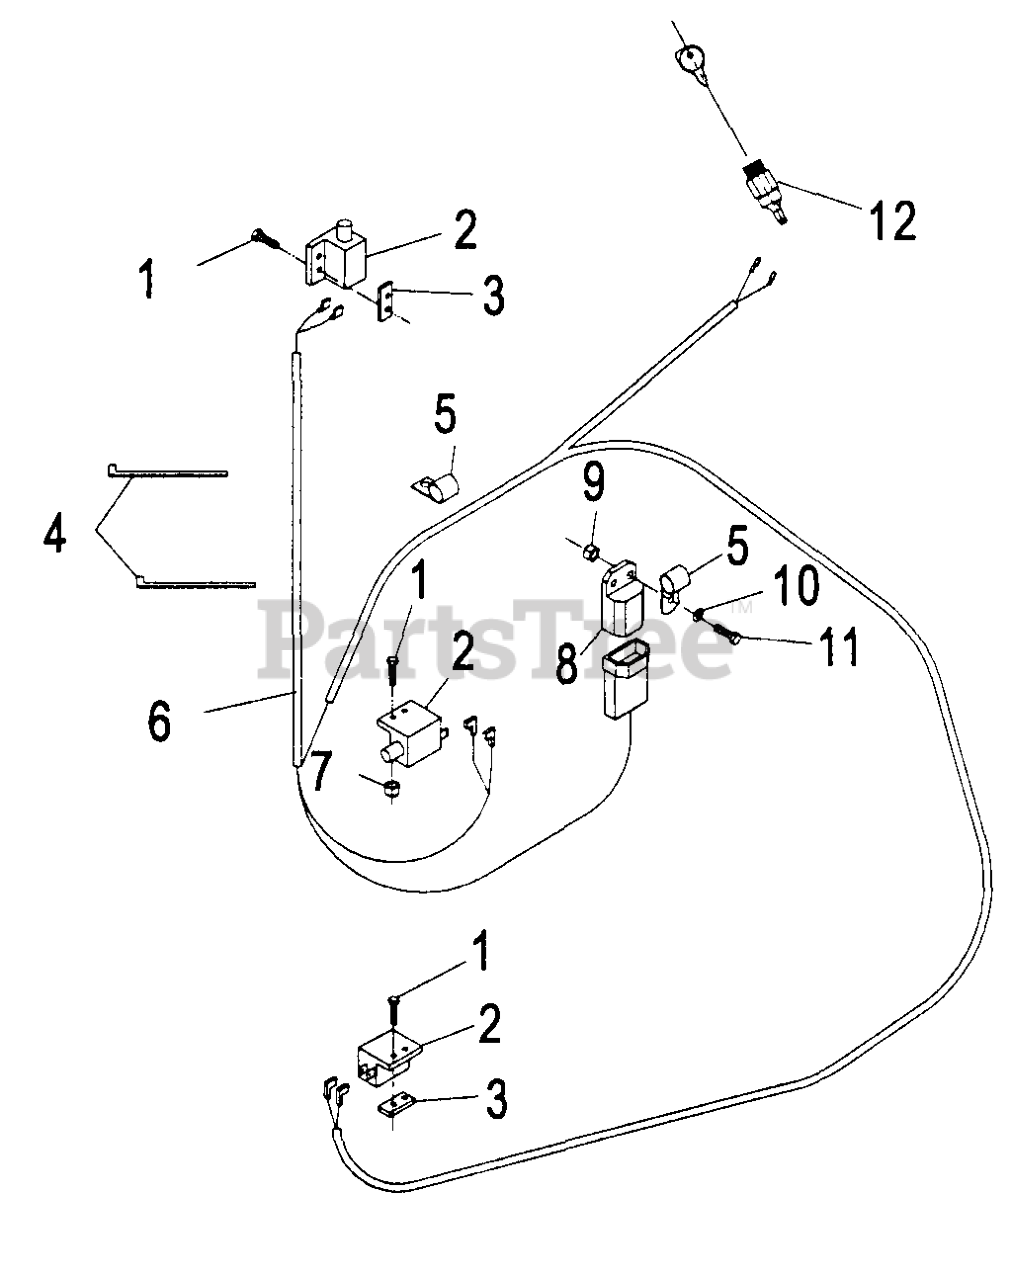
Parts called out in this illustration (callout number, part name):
2	SWITCH-OPEN, NORMALLY
3	PLATE-TAPPED
4	TIE-CABLE
5	CLIP-LOOM
6	HARNESS,WIRING KOHLER TT
7	NUT-SQH
8	MODULE-INTERLOCK
12	SWITCH & KEY (INCLUDES NU
